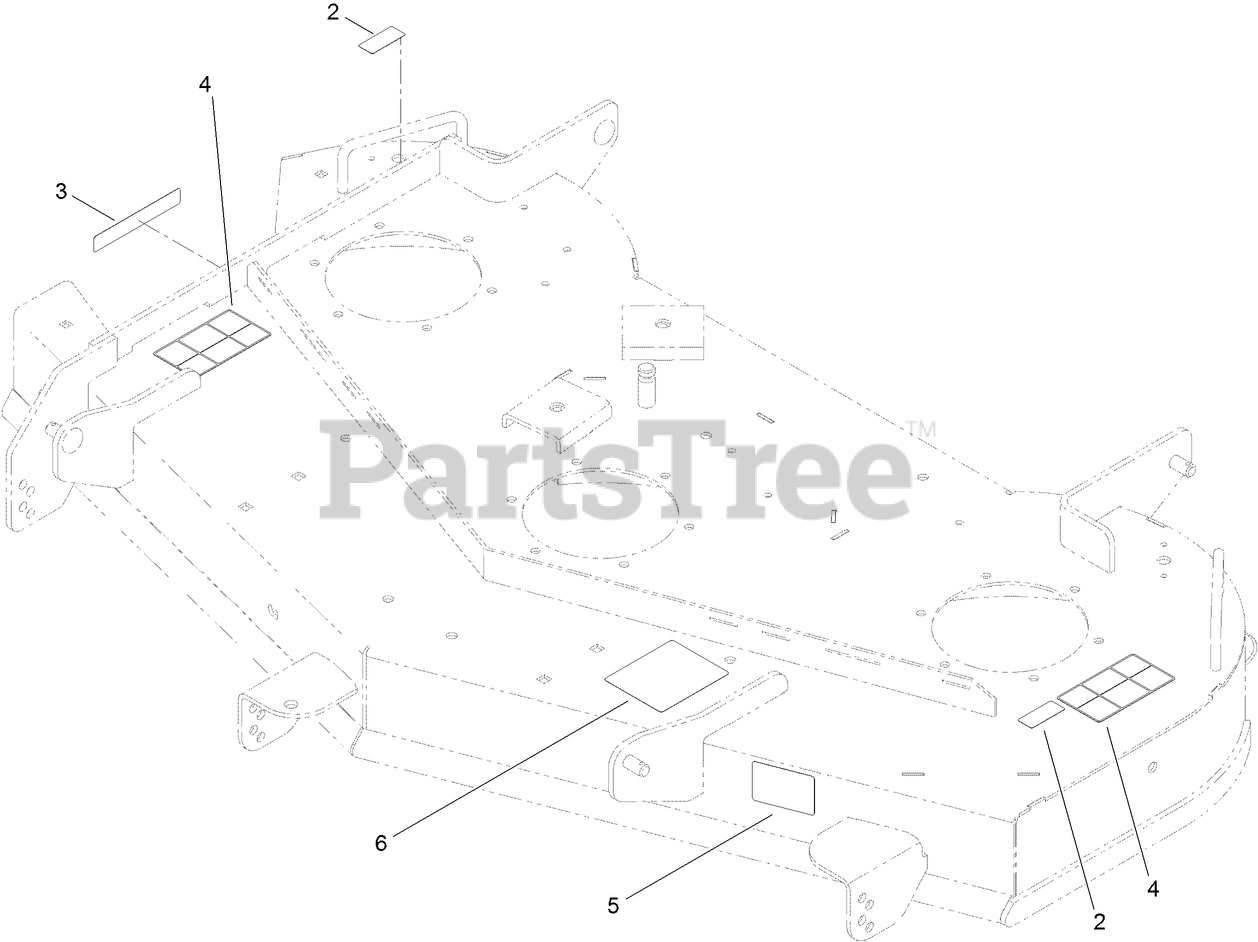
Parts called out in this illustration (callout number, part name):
2	DECAL-DANGER
3	DECAL-DANGER
4	DECAL-DANGER
5	DECAL-SCALP, ANTI
6	DECAL-ROUTING, BELT
